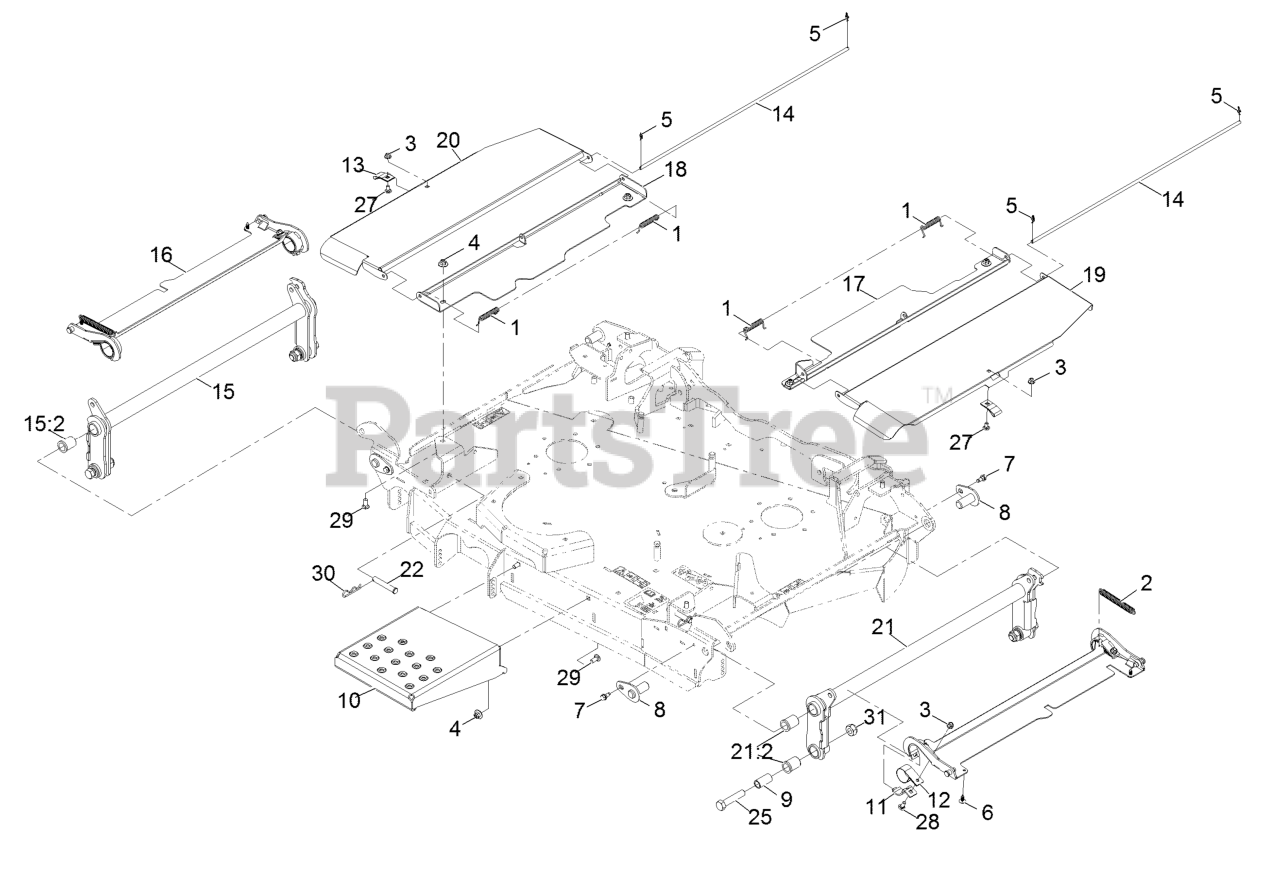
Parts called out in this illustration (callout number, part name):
3	Nut-Nyloc 5/16-18 Flg
4	Nut-Nyloc 3/8-16 Flg
5	Pin-Cotter, Locking
6	Plug-Plastic
7	Screw-Shoulder
8	Pin-Deck
9	Bushing-Float, Deck
10	Panel-Step
11	Plate-Retainer, Bearing
12	Bearing-Strap, Nylon
13	Bearing-Strap, Nylon
14	Cover-Rod, Pivot
15	RH Fold Arm ASM
15:2	Bushing-Flanged
16	Cover-Wing
17	Shield-Center, LH
18	Shield-Center, RH
19	Panel-Shield Hinge, LH
20	Panel-Shield Hinge, RH
21	LH Fold Arm ASM
21:2	Bushing-Flanged
22	Pin-Clevis
25	Screw-HH
27	Screw-CARR
28	Bolt-Carriage 5/16-18 X 7/8
29	Bolt-CARR
30	Pin-Hair
31	Nut-Lock
